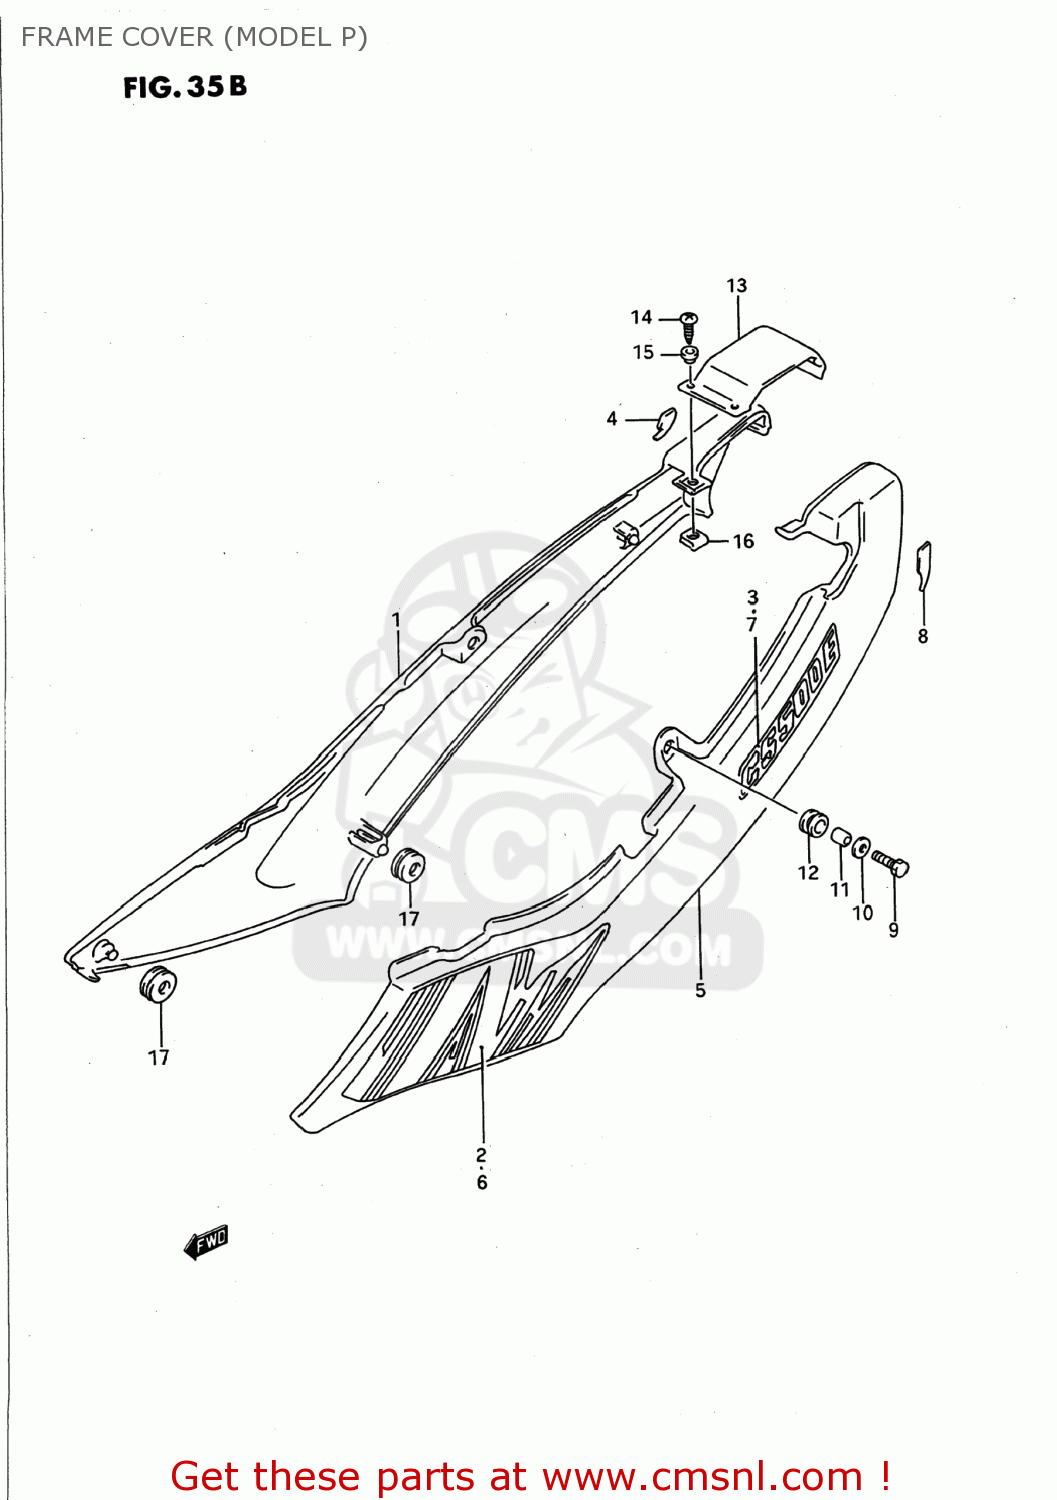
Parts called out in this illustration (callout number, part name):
1	COVER COMP,FRAME,RIGHT
2	TAPE,FRAME COVER,RIGHT
3	EMBLEM,FRAME COVER
4	PROTECTOR,FRAME COVER,R
5	COVER COMP,FRAME,LEFT
6	TAPE,FRAME COVER,LEFT
7	EMBLEM,FRAME COVER
8	PROTECTOR,FRAME COVER,L
9	BOLT(6X20)
10	WASHER
11	SPACER (6.1X9X9)
12	CUSHION
13	COVER,FRAME,CENTER
14	SCREW
15	WASHER(5.2X14X1.5)
16	NUT
17	CUSHION
